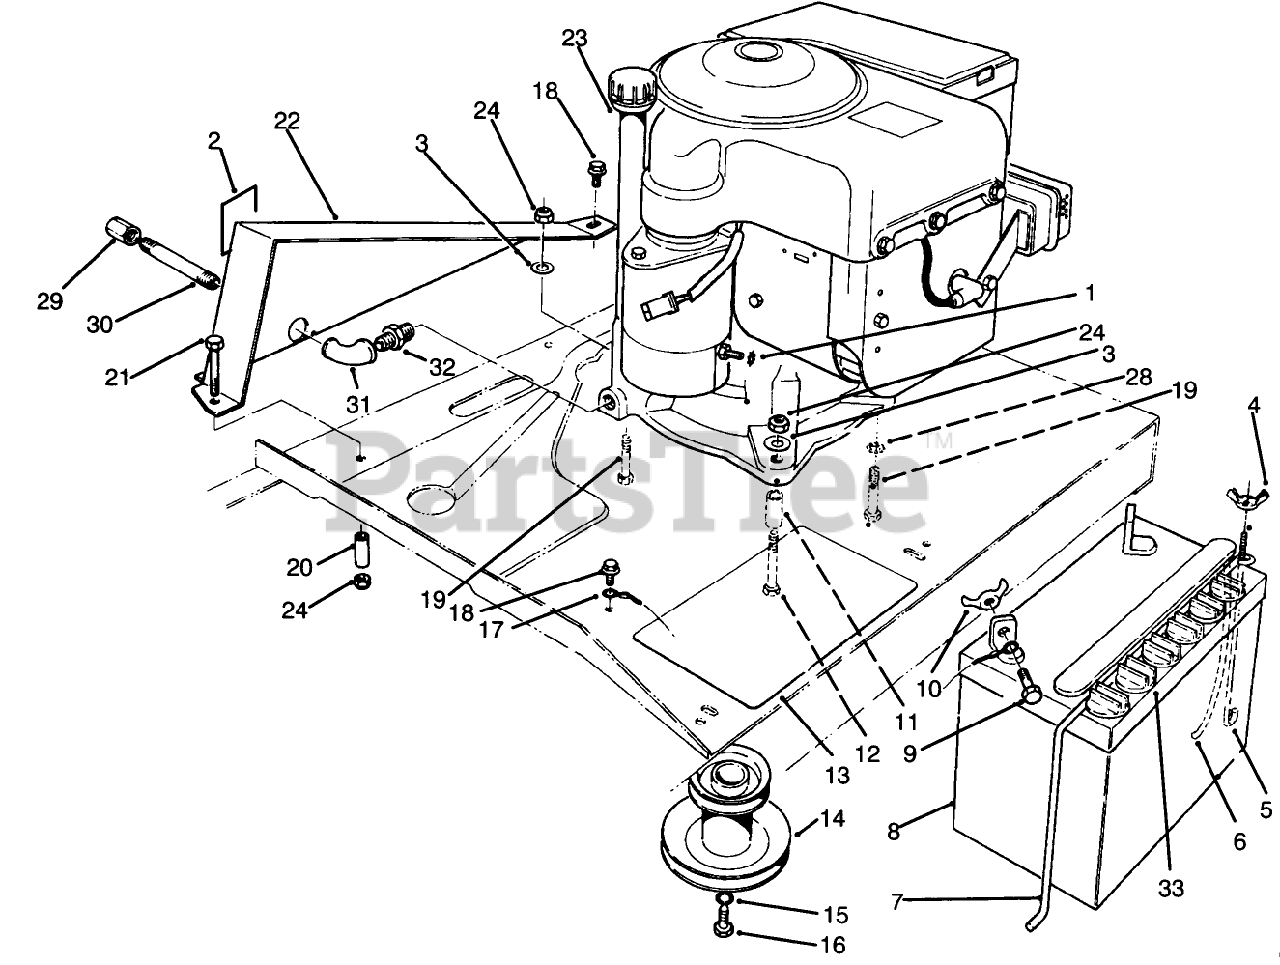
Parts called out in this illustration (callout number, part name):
1	WASHER-LOCK/EXT
3	WASHER-PLAIN
4	NUT-WING SPECL
6	TUBE-BATT DRAIN/80-2600
7	HOLDDOWN-BATTERY
9	SCREW-HH
10	NUT-WING
11	SPACER-PIVOT
12	SCREW-HH
13	PAD-SKID, ANTI
15	WASHER-FLAT
16	SCREW-HH
17	WIRE ASM(BATT/GRD.
18	SCREW-HWHTF
19	SCREW-HH
20	GUIDE-BELT
21	SCREW-HH
22	GUIDE-CHAIN
23	Engine-8 H.P. B S
24	NUT-LOCK, NI
28	WASHER-LOCK
29	CAP-PIPE
30	NIPPLE-PIPE
31	ELBOW-STREET
32	BUSHING-PIPE
